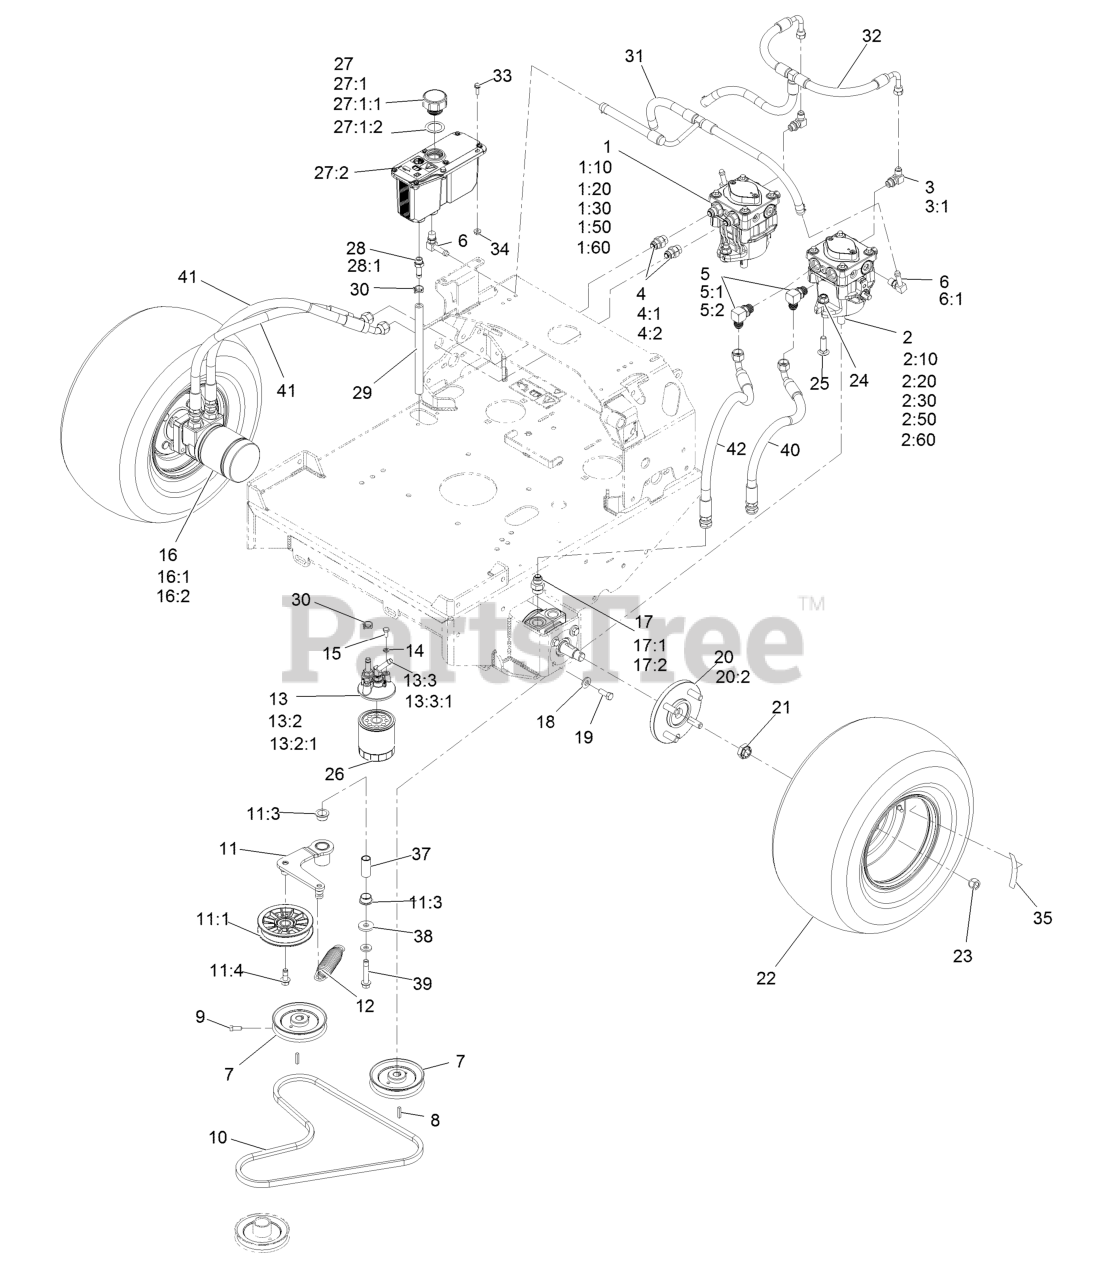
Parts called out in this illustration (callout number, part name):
1	Pump-HYD Pe RH TTH
1:10	Input Shaft Kit
1:20	Bearing-Thrust
1:30	Cylinder Block Kit
1:50	Seal Overhaul Kit
1:60	Kit, 10Cc Pump Kit
2	Pump-HYD Pe LH TTH
2:10	Input Shaft Kit
2:20	Bearing-Thrust
2:30	Cylinder Block Kit
2:50	Seal Overhaul Kit
2:60	Kit, 10Cc Pump Kit
3	Fitting-Elbow, 90 DEG
3:1	O-Ring
4	Adapter-Straight
4:1	O-Ring-SAE #8
4:2	O-Ring-37 Flare #8
5	Elbow-90deg
5:1	O-Ring-SAE #8
5:2	O-Ring-37 Flare #8
6	Fitting-Elbow, 90
6:1	O-Ring
7	Sheave ASM
8	Key-5Mm X 5Mm X 25Mm
9	Screw-Set, SQH 5/16-18 X 3/4
10	Belt
11	ASM, Pump Idler
11:1	Pulley-Idler, Flat
11:3	Bushing-Flanged
11:4	Screw-Hfh
12	Spring-Extension
13	ASM, Filter Head
13:2	Adapter-Straight
13:2:1	O-Ring
13:3	Fitting-Barbed, 45 DEG
13:3:1	O-Ring
14	Washer-Lock 1/4 Heavy
15	Screw-HH 1/4-20 X 5/8
16	HYD Motor ASM
16:1	Seal Kit
16:2	Bearing And Seal Kit
17	Adapter-Straight
17:1	O-Ring
17:2	O-Ring-37 Flare #8
18	Washer-Spring Disc 3/8
19	Screw-HH 3/8-16 X 1
20	Wheel Hub ASM
20:2	Stud-Wheel
21	Nut-Lock
22	Tire And Wheel Assy
23	Nut-Lug 1/2-20
24	Nut-HF, NI
25	Bolt-Carriage 7/16-14 X 1 1/2
26	Element, Oil Filter
27	ASM, HYD Reservoir
27:1	Reservoir-HYD
27:1:1	Cap-Reservoir, HYD
27:1:2	Gasket-Cap
27:2	Decal-Warning
28	Adapter-Straight
28:1	O-Ring
29	Hose-Charge
30	Clamp-Hose 11/16
31	Hose, Case
32	Hose, Charge
33	Screw-Machine 1/4-20 X 3/4
34	Nut-Whizlock 1/4-20
35	Decal-Torque Wheel Lug-Hub
37	Pivot, Idler
39	Screw-HHF W/ Patch
40	ASM, HP Hose
41	Hose,Hydraulic W/Cover
42	HYD Hose ASM
